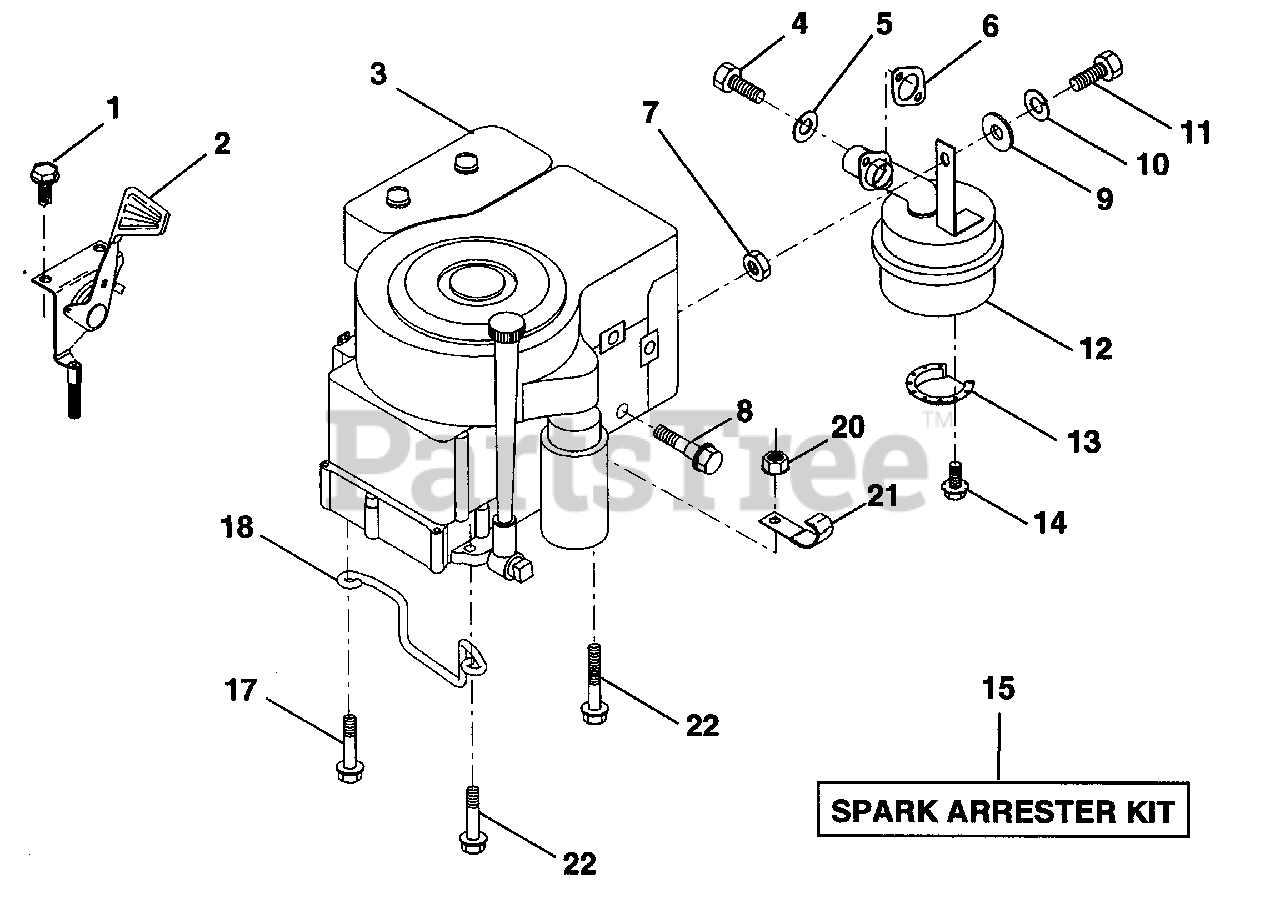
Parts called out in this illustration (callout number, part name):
1	Screw, Hex Head, Thread Cutting 1/4-20 x 1/2 (AYP part number)
2	Control, Throttle
4	Screw, Hex Cap Head, 5/16-18 x 3/4 (AYP part number)
5	Washer, Lock, Heavy Helical Spring 5/16 (AYP part number)
6	Gasket, Exhaust (AYP part number)
7	Nut, Hex, Fin. 5/16-18 (AYP part number)
8	Bolt, Shoulder (AYP part number)
9	Washer 5/16 x 3/4 x 16 Gauge (AYP part number)
10	Washer, Lock, Heavy Helical Spring 1/4 (AYP part number)
11	Bolt, Hex, Fin. 1/4-20 UNC x 3/4 (AYP part number)
12	Muffler (AYP part number)
13	Deflector, Muffler (AYP part number)
14	Screw, Hex Head, Spiderlock #8 x 1/2 ABTPS (AYP part number)
15	Kit, Spark Arrester (Optional) (AYP part number)
17	Screw, Hex Washer Head, Thd. Roll. 3/8-16 x 1-1/2 (AYP part number)
18	Keeper, Ground Drive Belt (AYP part number)
20	Nut, Keps 3/8-16 (AYP part number)
21	Clip, Fuel Line (AYP part number)
22	Screw, Thd. Roll. 3/8-16 x 2 (AYP part number)
